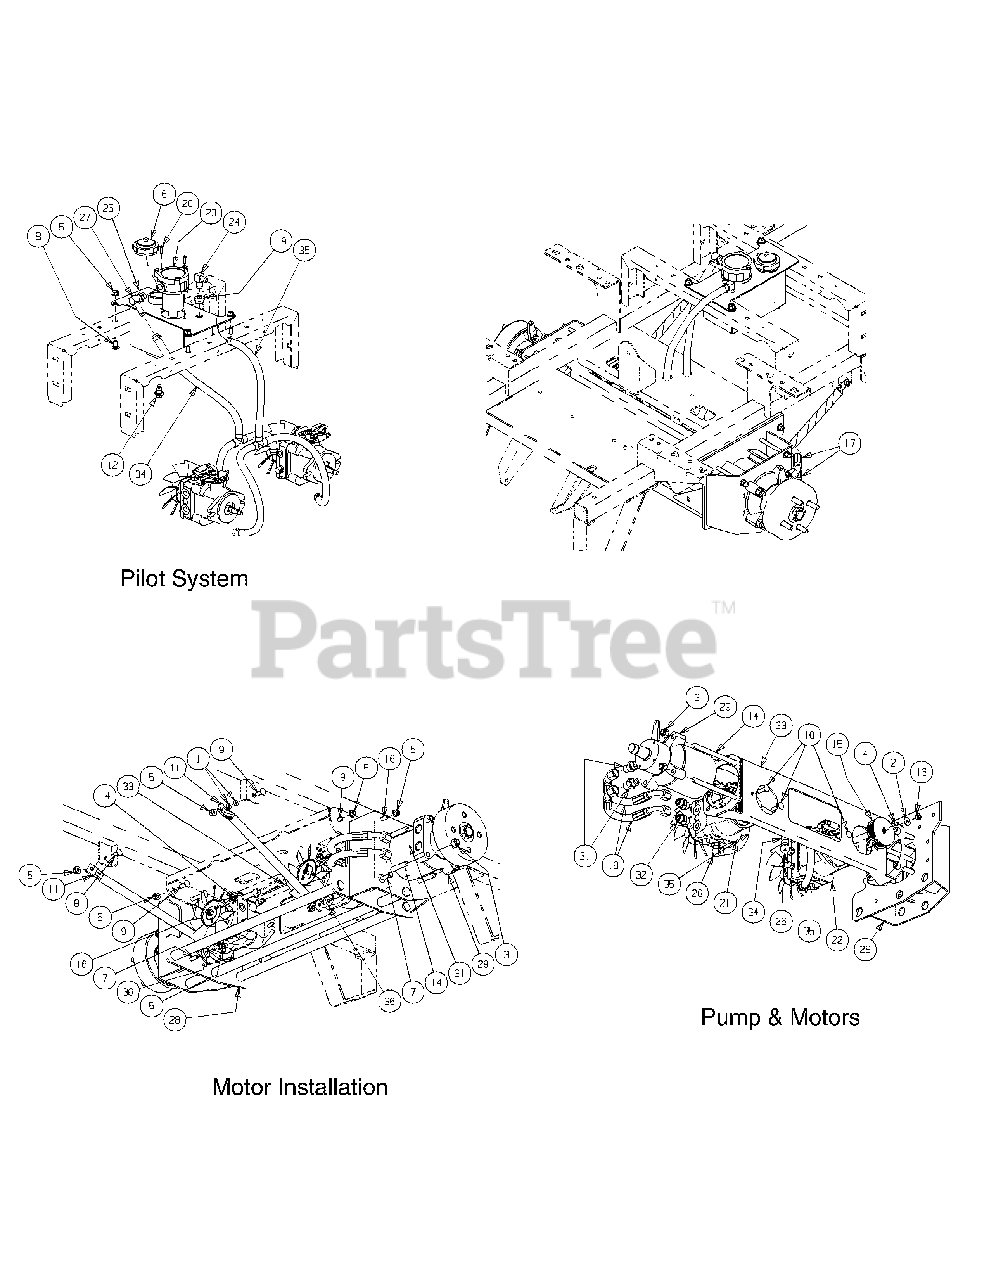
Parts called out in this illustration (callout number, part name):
1	Washer lock 3/8 zinc
2	Flat Washer, 3/8
3	Washer lock 3/8 zinc
4	Key, 3/16" x 7/8"
5	Flange Lock Hex Nut, 3/8-16
6	Cap, Hydro Oil Tank
7	Hex Cap Screw, 3/8 -16 x 1.25
8	Carriage Bolt, 3/8-16 x .75 LG.
9	Carriage Bolt, 3/8-16 x 1
10	Carriage Screw, 3/8-16 x 1.25
12	Oil Pan Drain Plug w/ Seal
13	Hex Nut, 3/8-24
14	Socket Head Capscrew, 1/2-13; 6-1/2
15	Hydro Pulley Pump
16	Carriage Bolt, 3/8-16 x 5.0
17	Hose Assembly, RH
18	Hose Assembly, LH
19	Grommet Fitting, .54 ID x .78 OD
20	Socket Low Head Cap Screw, 1/4-20 x 0.75
21	Hydro Pump, BDP-12, LH
22	Hydro Pump, BDP-12, RH
23	Hydraulic In-Tank Filter includes:
24	Fitting Elbow Spur, 5/8 x 1/2
25	Hydraulic Tank Assembly
26	Fitting Elbow, 9/16 x 1/2
27	Fitting Elbow, 3/4 x 1/2
28	Hydro Motor Frame Assembly
29	Hydro Motor, Left Hand Assembly w/Brake & Drum
30	Hydro Motor, Right Hand Assembly w/Brake & Drum
31	Adaptor Fitting, 8 x 10
32	Adaptor Fitting, 8 x 8
33	Hydro Pump Mounting Bracket
34	Hose Assembly, Pilot includes:
35	Hose Assembly, Drain includes:
36	Spacer .406 ID x 1.0 OD
